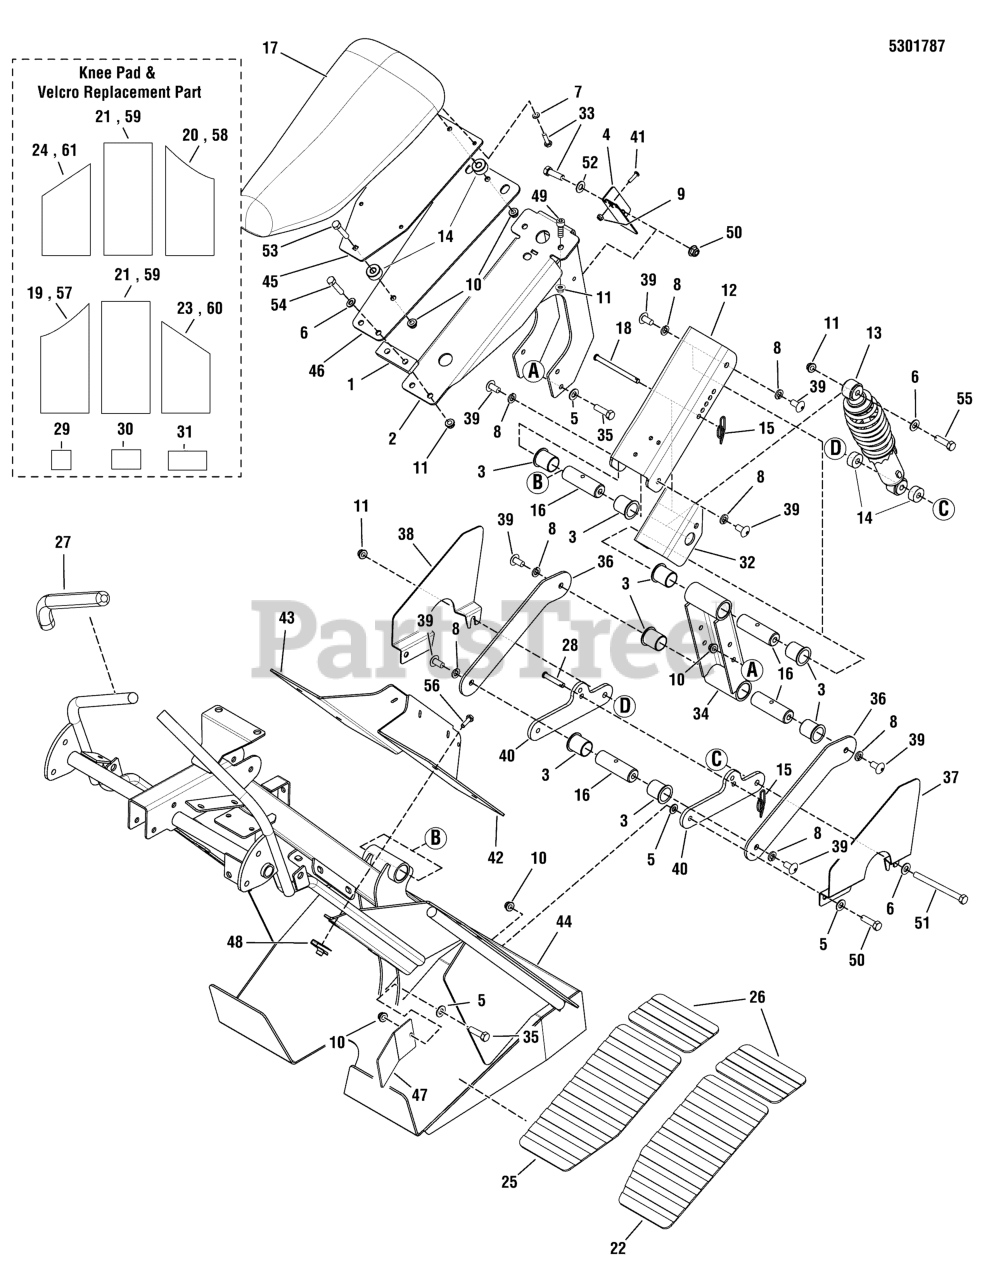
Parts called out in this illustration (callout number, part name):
1	SPACER, .38 X 1.00 X 3.25 - RED
2	WELD, SEAT MAIN, SNP PRO - RED
3	BUSHING, 1.00 X 1.13 X 1.38, PLASTIC
4	PLATE, SWITCH MOUNT - RED
5	WASHER, 5/16" SAE
6	WASHER, 3/8 SAE
7	WASHER, 1/4 LOCK
8	WASHER, 3/8 SPLIT LOCK
9	NUT, #10-24 HEX NYLON LOCK
10	NUT, 5/16-18 HEX NYLOCK FLANGE
11	NUT, 3/8-16 HEX NYLOCK FLANGE
12	PLATE, SEAT MOUNT, TOP - RED
13	SHOCK,# 7417-104, FRONT, IS4500
14	SPACER, .39 X 1.00 X .50
15	PIN, SURE LOCK COTTER, .09 X .75, YZ
16	SPACER, 1.00 X 3.25 THRD BOTH ENDS
17	SEAT, EVOLUTION
18	PIN, CLEVIS, 5/16 X 4.00, YZ
19	KNEE PAD, INNER RH, EVOLUTION 36"/48"
20	KNEE PAD, INNER LH, EVOLUTION 36"/48"
21	KNEE PAD, CENTER, EVOLUTION 36"/48"
22	SAFETY WALK, EVOLUTION 36"
23	KNEE PAD, OUTER RH, EVOLUTION 48/52
24	KNEE PAD, OUTER LH, EVOLUTION 48/52
25	SAFETY WALK, 6.00 X 11.25
26	SAFETY WALK, 3.5 X 6.00
27	FOAM, GRIP, 3/4" ID X 12" LG X .187 BLK
28	PIN, CLEVIS, 5/16 X 2-3/4, PLATED
29	VELCRO, 2" X 2", HOOK MATERIAL
30	VELCRO, 2" X 3", HOOK MATERIAL
31	VELCRO, 2" X 4", HOOK MATERIAL
32	WELD, MOUNT, SHOCK, SEAT - RED
33	BOLT, 1/4-20 X 1" GD5 CZ
34	WELD, MOUNT, SEAT ADJUSTABLE - RED
35	BOLT, 5/16-18 X 1 GD5 YZ
36	PIVOT, SUSPENSION SEAT, SNP PRO - RED
37	GUARD, FOOT, RH, S75X - RED
38	GUARD, FOOT, LH, S75X - RED
39	BOLT, 3/8-16 X 3/4,ALLEN BUTTON
40	PIVOT, ADJUSTMENT, SEAT - RED
41	SCREW, #10-24 X 3/4 ROUND PHILLIPS
42	PLATE, KNEE, LH, SNP PRO - RED
43	PLATE, KNEE, RH, SNP PRO - RED
44	WELD, OPERATOR COMPARTMENT - RED
45	PLATE, SEAT RAIL ADAPTER - RED
46	PLATE, SEAT MOUNT - RED
47	GUARD, FOOT, EVO 36-48 - RED
48	BODY CLIP, 1/4-20 X 1/2 DEEP
49	BOLT, 3/8-16 X 3/8, 1/2 SHOULDER
50	NUT, 1/4-20 NYLK FLNG
51	BOLT, 3/8-16 X 3-1/2" GD5 CZ
52	WASHER, 1/4 SAE
53	BOLT, 5/16-18 X 1-3/4, CARRIAGE
54	BOLT, 3/8-16 X 1-1/4" GD5 CZ
55	BOLT, 3/8-16 X 2, GD5, CZ
57	KNEE PAD, INNER RH, S75X
58	KNEE PAD, INNER LH, S75X
59	KNEE PAD, CENTER, S75X
60	KNEE PAD, OUTER RH, S75X
61	KNEE PAD, OUTER LH, S75X
